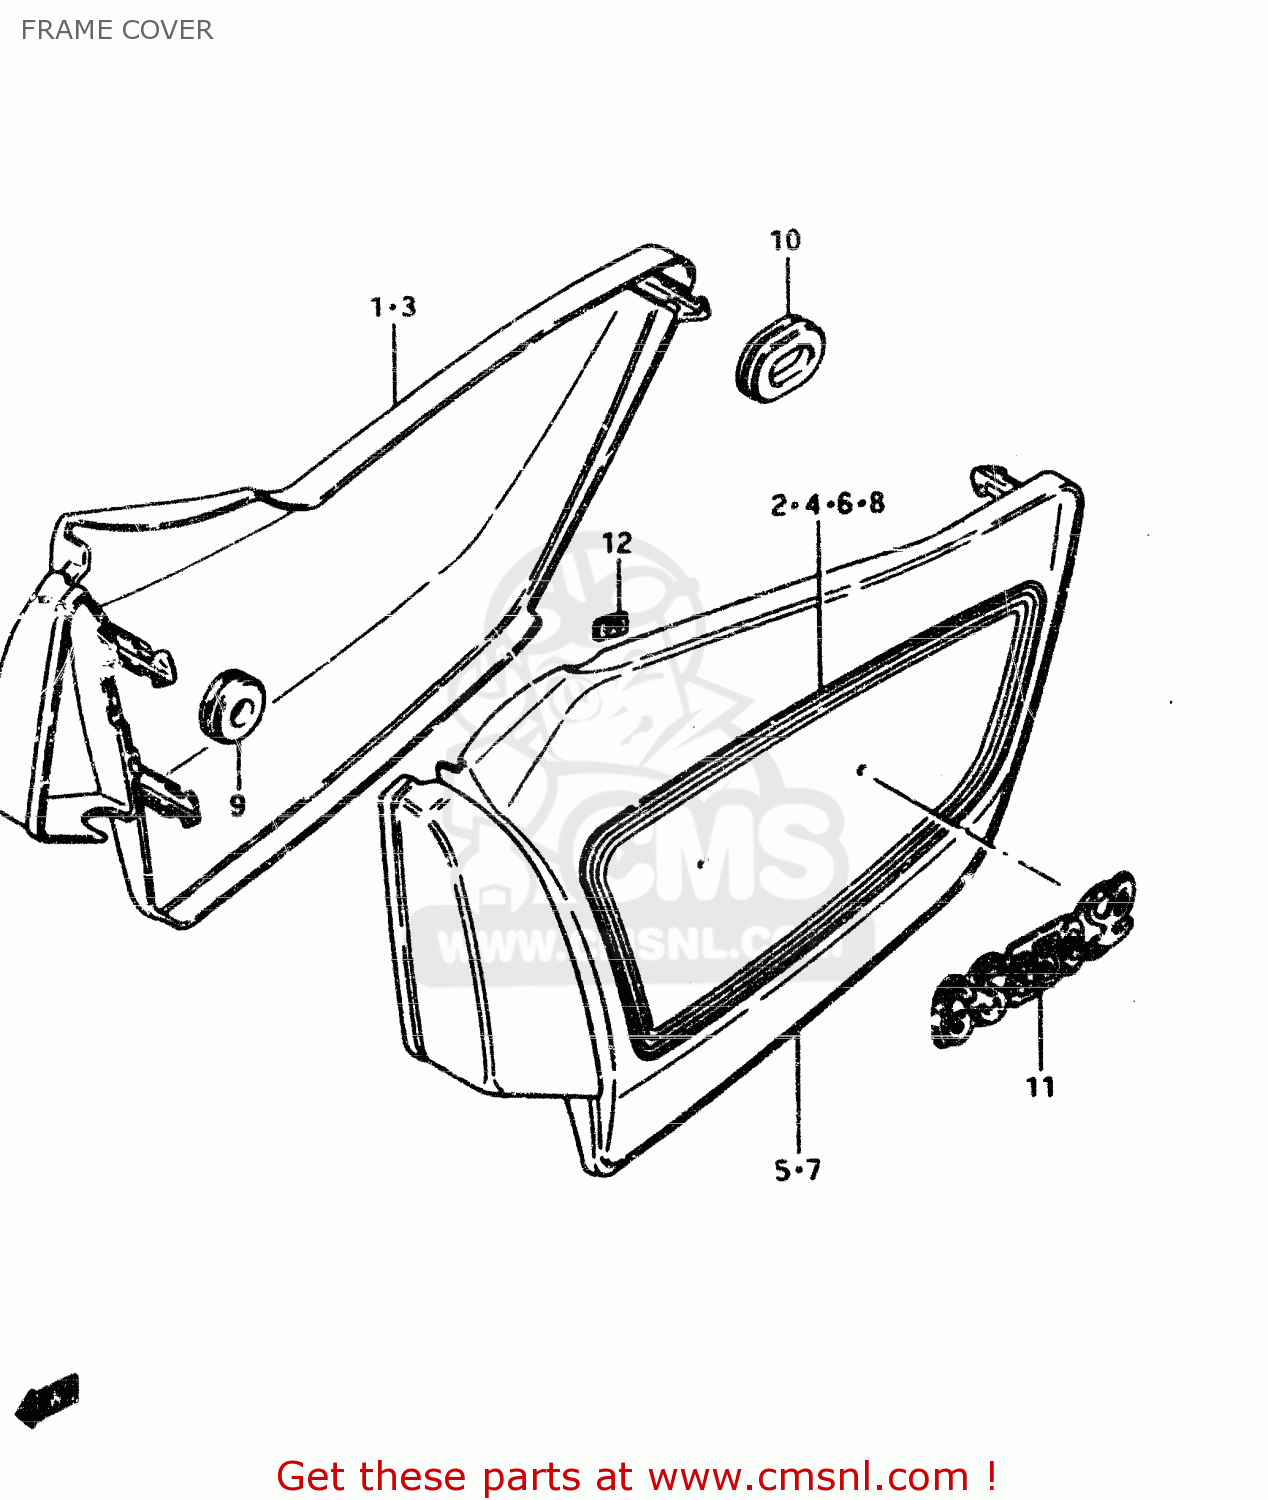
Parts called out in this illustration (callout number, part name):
1	COVER,FRAME,RIGHT
2	TAPE SET,FRAME COVER
3	COVER,FRAME,RIGHT
4	TAPE SET,FRAME COVER,RIGHT
5	COVER,FRAME,LEFT
6	TAPE SET,FRAME COVER
7	COVER,FRAME,LEFT
8	TAPE SET,FRAME COVER
9	CUSHION
10	CUSHION
11	EMBLEM,FRAME COVER
12	NUT
